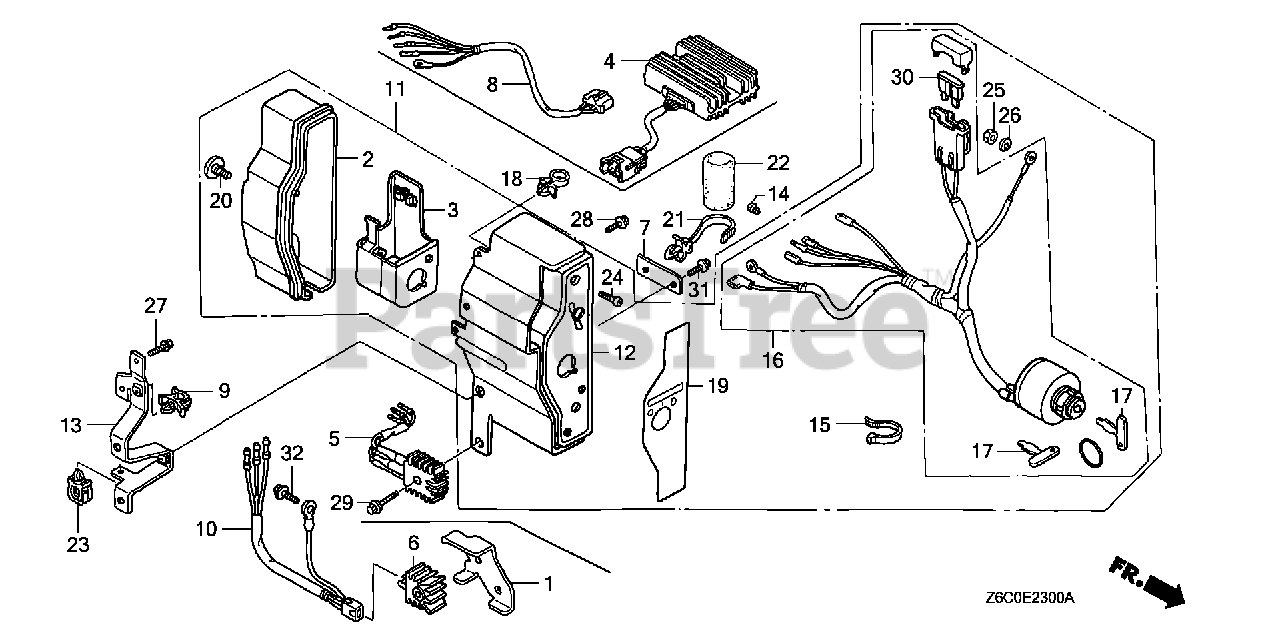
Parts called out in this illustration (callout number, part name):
2	CASE, CONTROL
3	BRACKET, CASE MOUNTING
4	RECTIFIER ASSY., REGULATOR (20A)
7	BRACKET, WIRE HARNESS CLIP
8	SUB-WIRE HARNESS ASSY.
9	CLIP, WIRE HARNESS
11	BOX ASSY., CONTROL
12	PANEL, CONTROL
13	STAY, CONTROL BOX
15	BAND
16	SWITCH ASSY., COMBINATION
17	KEY
18	HOLDER, STOP SWITCH WIRE Use up to Engine SN 2056819.
19	MARK, CONTROL BOX (EXP)
20	SCREW, SPECIAL (6X12)
21	BAND, WIRE HARNESS (150MM) (Honda Code 1352103). (BLUE)
21	CLIP, WIRE HARNESS *NH1L* (BLACK)
22	TUBE, CORD (30MM)
23	CLIP, WIRE HARNESS
24	SCREW, PAN (4X12)
25	NUT, HEX. (4MM)
26	WASHER, SPRING (4MM)
27	BOLT, FLANGE (6X10)
28	BOLT, FLANGE (6X12) Use up to Engine SN 1543277.
30	FUSE, BLADE (25A)
31	BOLT, FLANGE (6X10)
31	BOLT, FLANGE (6X12) Use up to Engine SN 1543277.
